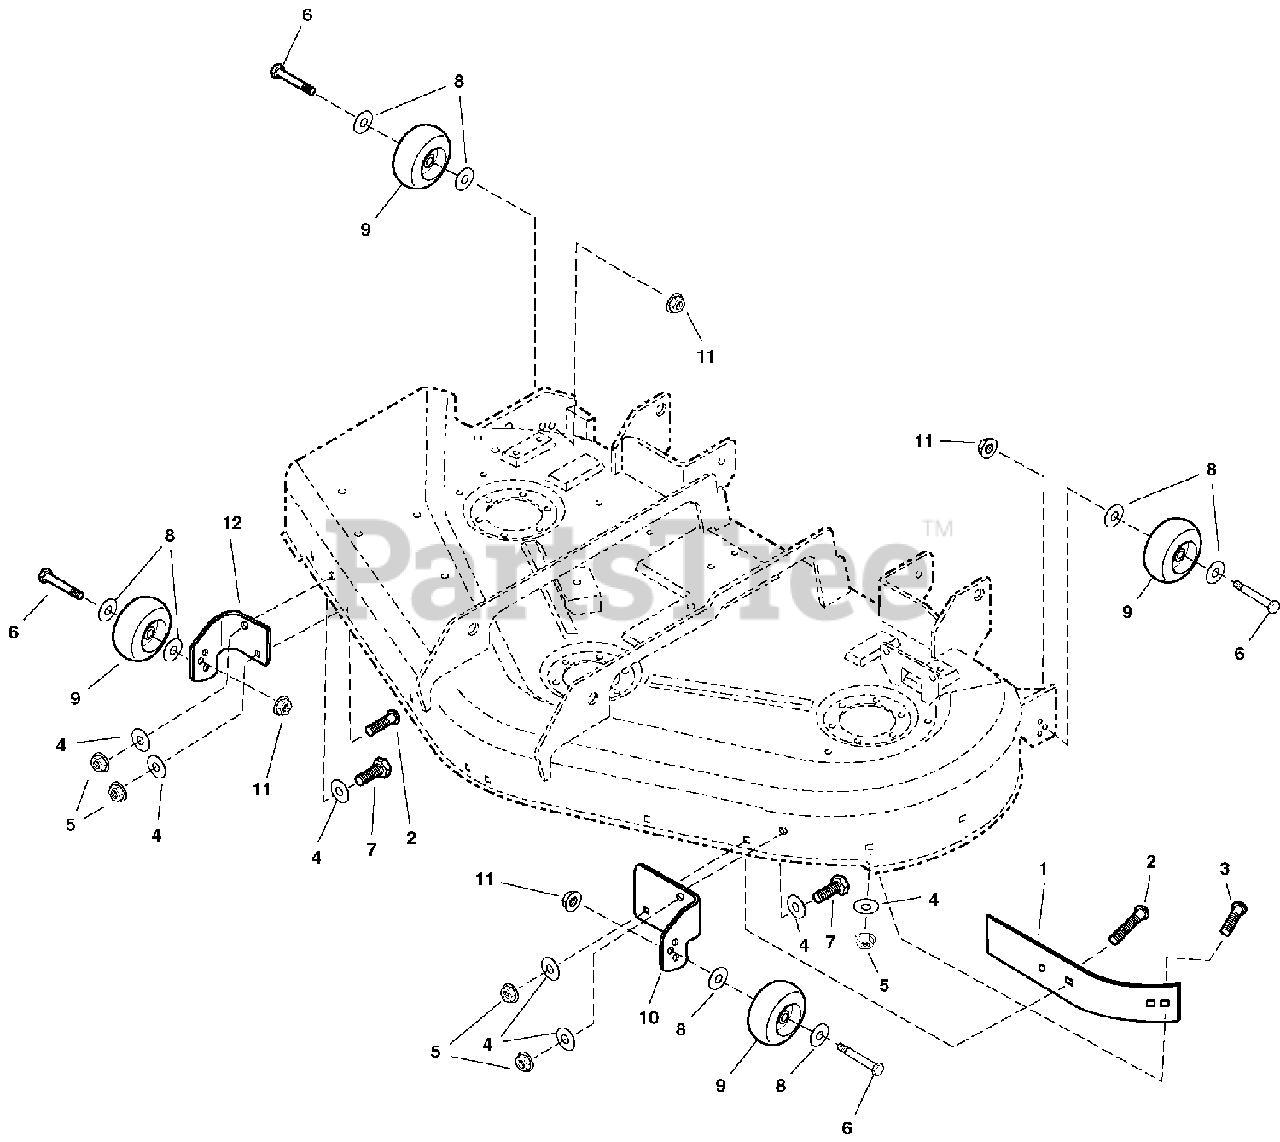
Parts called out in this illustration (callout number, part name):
1	SHORT BLOWOUT BAFFLE
2	CARRIAGE BOLT, 5/16-18 X 1
3	CARRIAGE BOLT, 5/16-18 X 3/4
4	WASHER, 5/16, PLAIN, SAE
5	NUT, 5/16-18, HEX, NYLON LOCK
6	BOLT, REAR WHEEL
7	CAPSCREW, HEX HEAD, 5/16-18 X 1
8	WASHER
9	GAUGE, WHEEL
10	BRACKET, GAUGE WHEEL, LH
11	NUT, FLANGE, SIDELOCK, 3/8-16
12	BRACKET, GAUGE WHEEL, RH
